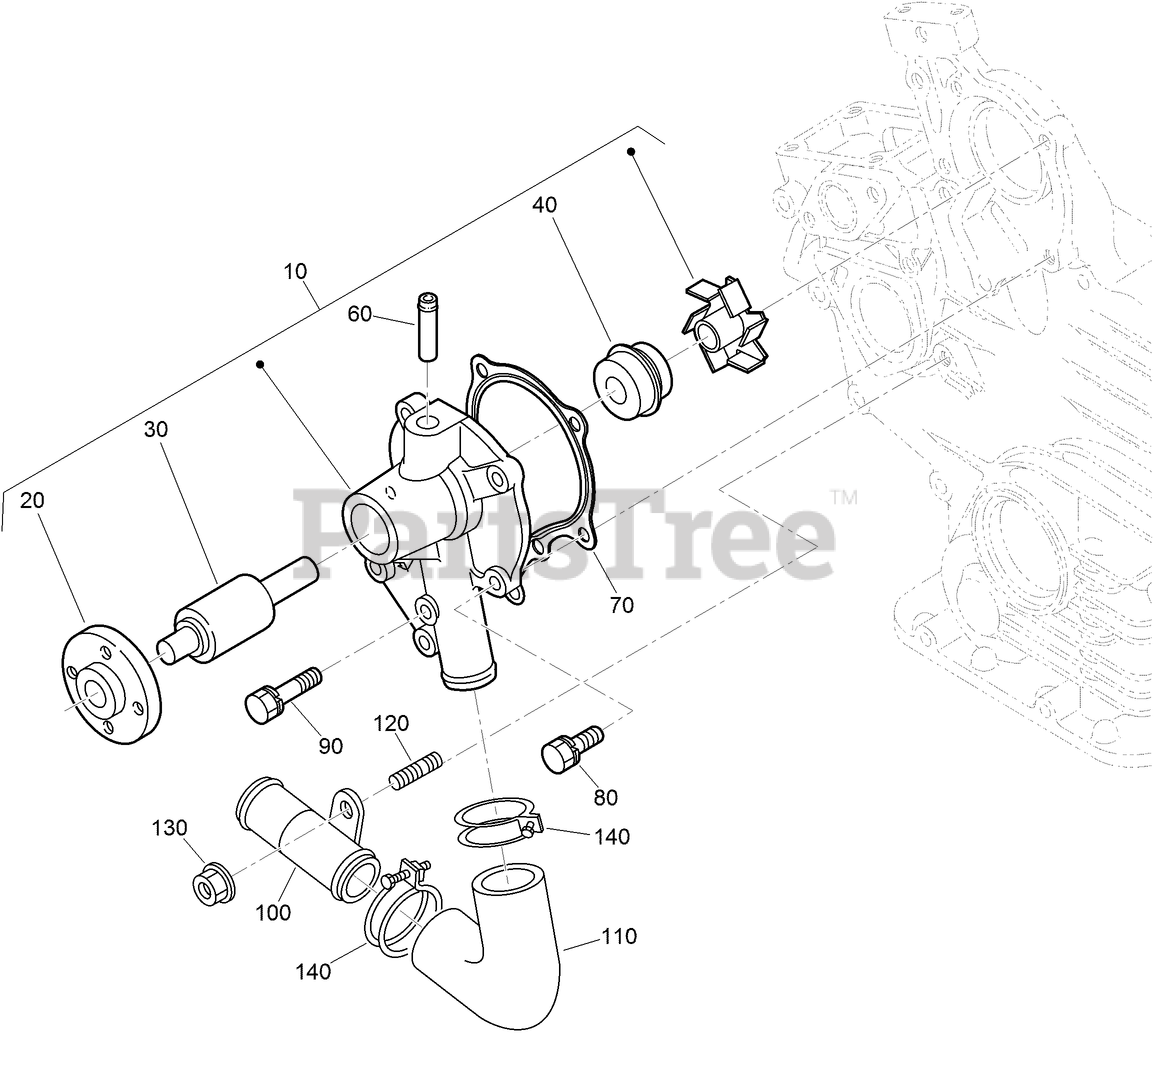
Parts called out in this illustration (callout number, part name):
10	WATER PUMP ASM
20	FLANGE-PUMP, WATER
30	BEARING-BALL
40	WATER PUMP SEAL ASM
60	PIPE-RETURN, WATER
70	GASKET-PUMP, WATER
100	PIPE-WATER
110	HOSE-WATER
130	NUT-FLANGE
140	BAND-PIPE
